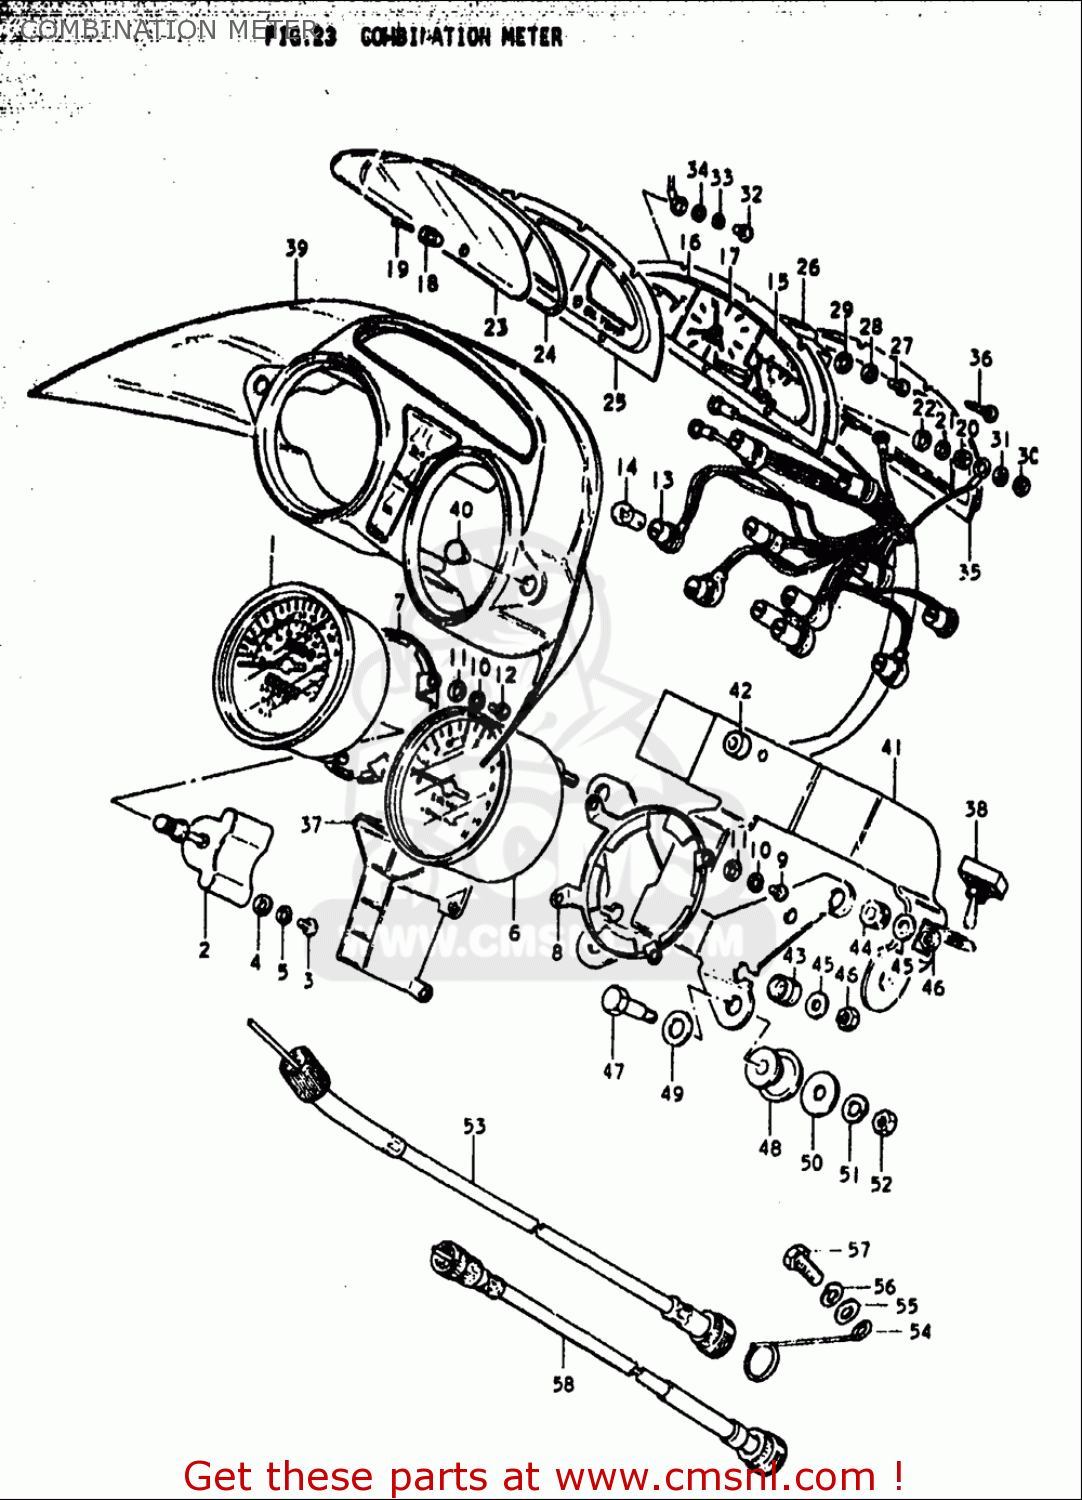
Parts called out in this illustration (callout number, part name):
3	SCREW
4	WASHER
5	WASHER,LOCK
9	SCREW
10	WASHER,LOCK
11	WASHER
14	BULB(12V3.4W,STANLEY,A72A)
20	NUT
21	WASHER,LOCK
22	WASHER
27	SCREW
28	WASHER,LOCK
29	WASHER
30	NUT
31	WASHER,LOCK
